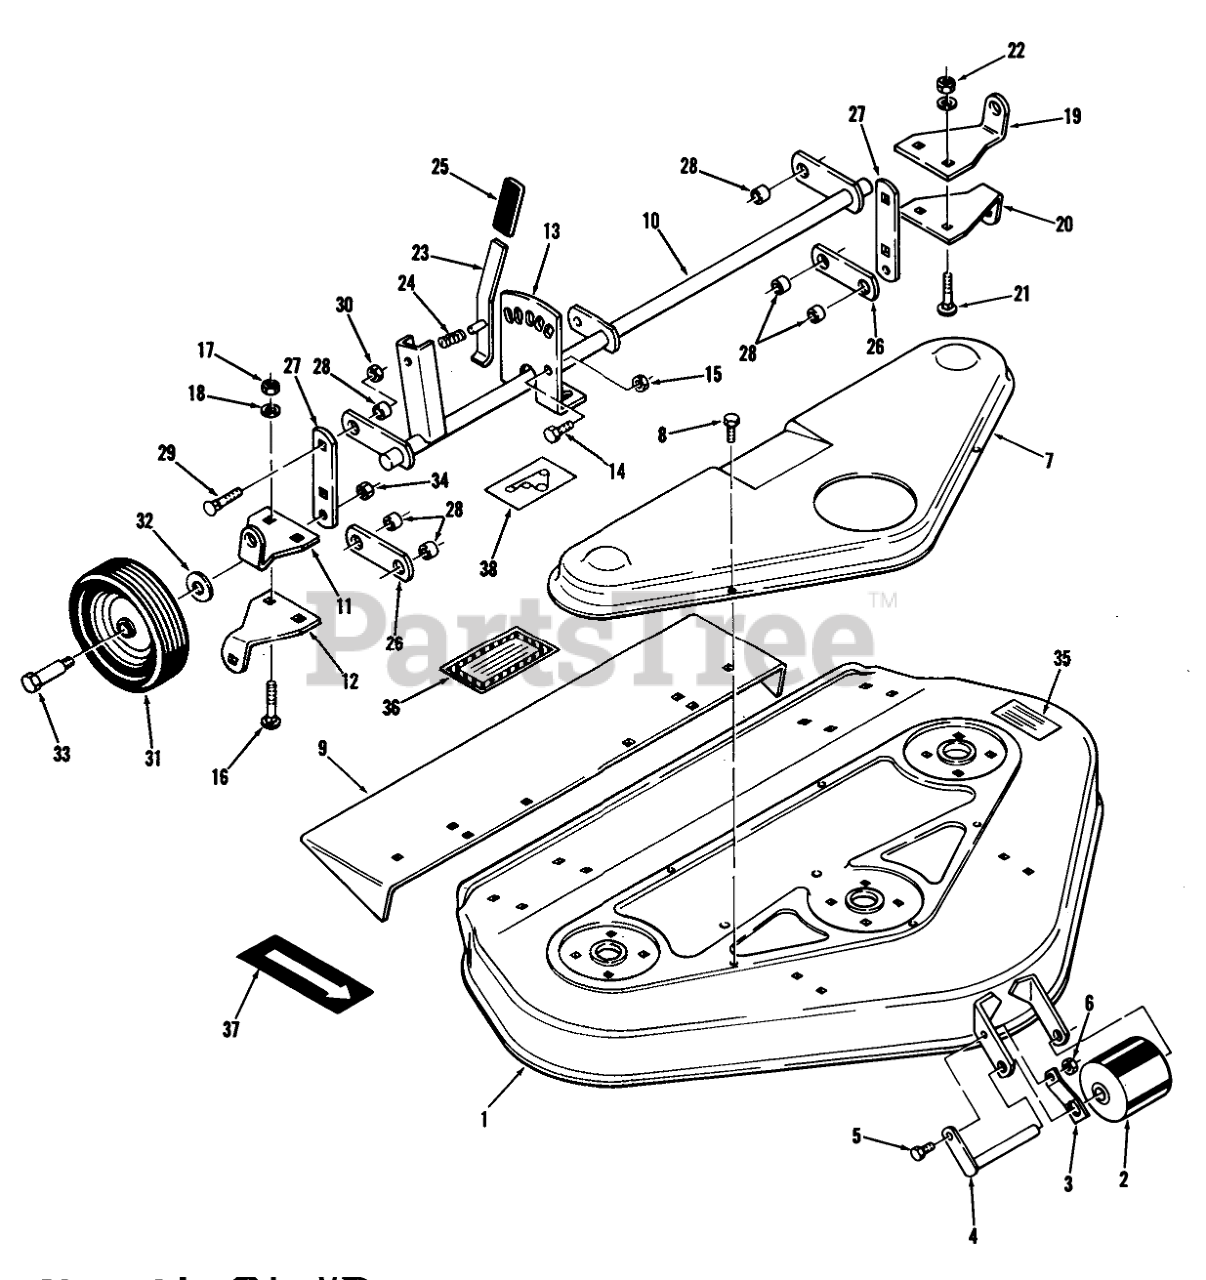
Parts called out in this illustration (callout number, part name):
1	Mower Deck-Rear Discharge
1	Mower Deck-Side Discharge
2	Roller
3	SPRING ROLLER STOP
4	Roller Shaft
5	H H C S
6	Nut
7	Belt Cover
8	Bolt
9	Extension-Chute
10	Gage Wheel Support Assy.
11	Bracket-R.H. Upper
12	Bracket-Lower R.H.
13	Quadrant
14	Bolt
15	Nut
16	Bolt
17	Nut
18	Washer
19	Bracket-L.H. Upper
20	Bracket-L.H. Lower
21	Bolt
22	Nut
23	Lever
24	SPRING-COMPRESSION
26	SUPPORT LINK R
27	WHEEL SUPPORT LINK
28	SPACER
29	Bolt
30	LOCKNUT-FLANGE
31	Wheel
32	WASHER
33	BOLT-SHOULDER
34	Nut
35	Caution Decal
36	Guard Decal
37	Decal-Edge of Cut
38	Decal Belt Diagram
